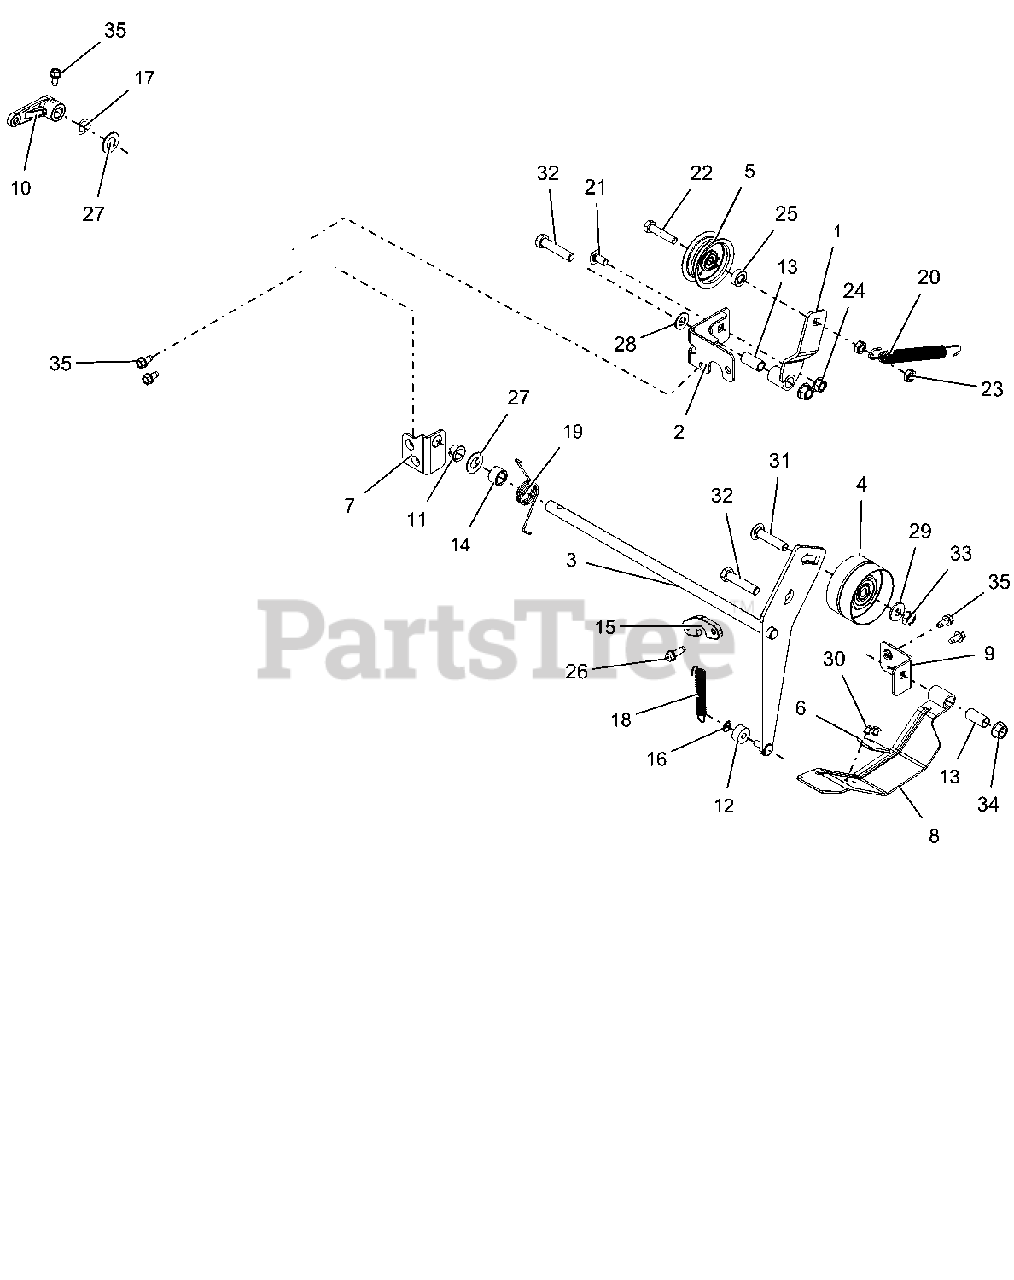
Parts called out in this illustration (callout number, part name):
1	ARM, TRACTION IDLER
2	WELDMENT, FRAME BRACKET
3	WELDMENT, ATTACHMENT IDLER ARM
4	IDLER, FLAT-2.75 OD X .375 ID
5	IDLER, FLAT - 2.00"
6	PAD, BRAKE
7	BRACKET, MOUNT - IDLER ARM
8	BRAKE ARM W/PAD
9	BRACKET, BRAKE MOUNT
10	ARM, CLUTCH - ATTACHMENT
11	BUSHING, POLYLINER-.50 SPLIT
12	BSHG,SLV .265 X .625 X .375
13	BSHG-SLV .385X.500X1.045
14	BSHG-SLV .510X.751X.475
15	SPACER, SWING GATE
16	RG-RTNG-EXT .250X.010
17	WSHR-WAVE .50X.75X.015 .13FRHT
18	SPRING-EXT .047 X .438 X 1.85
19	SG-TORS .075 X .955
20	SPRING, SWIVEL HOOK EXTENSION
21	@BLT-RHDSSQNK .31-18X.62 G5YZ
22	@BLT-HEX .31-18X1.50 GR5 YWZC
23	@NUT-LK-CTR-JAM .31-18 YWZC
24	@NUT-LK-TOP-FLG .31-18 YWZC
25	SPCR, BRG .315X.500X.358X.281
26	SCR-TAP-PM .25-20X.75 TR YWZ
27	WSHR-FL-STL.531X1.00X.063 YWZC
28	@WSHR-FL-STL.406X.812X.065 YWZ
29	@WSHR-FL-STL.38X.875X.083 YWZC
30	RVT-POP .187 YZ
31	@BLT-RHDSSQNK .38-16X1.75 G5YZ
32	@BLT-HEX .38-16X1.75 GR5 YWZC
33	@NUT-LK-CTR-JAM .375-16 YWZC
34	@NUT-LK-TOP-FLG .38-16 YWZC
35	SCR-TAP .25-20X.50 HWH TR YWZ
